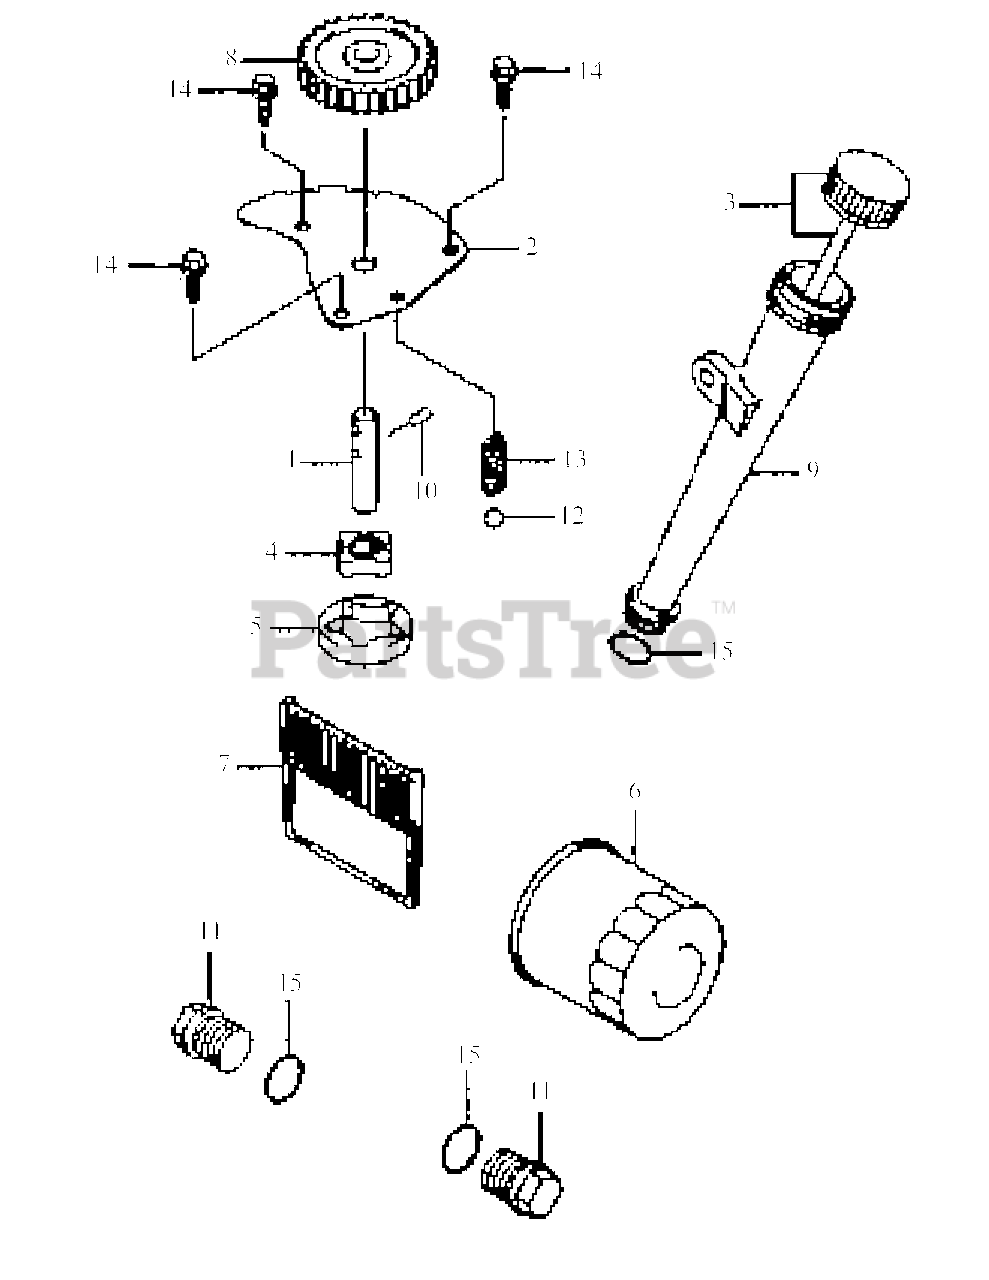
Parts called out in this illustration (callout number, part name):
1	Shaft, Oil Pump
3	Cap Assembly
4	Rotor, Pump In
5	Rotor, Pump Out
6	Filter, Oil
7	Filter, Oil Screen
8	Gear, Spur
10	Pin
11	Plug
14	Bolt, Flange
